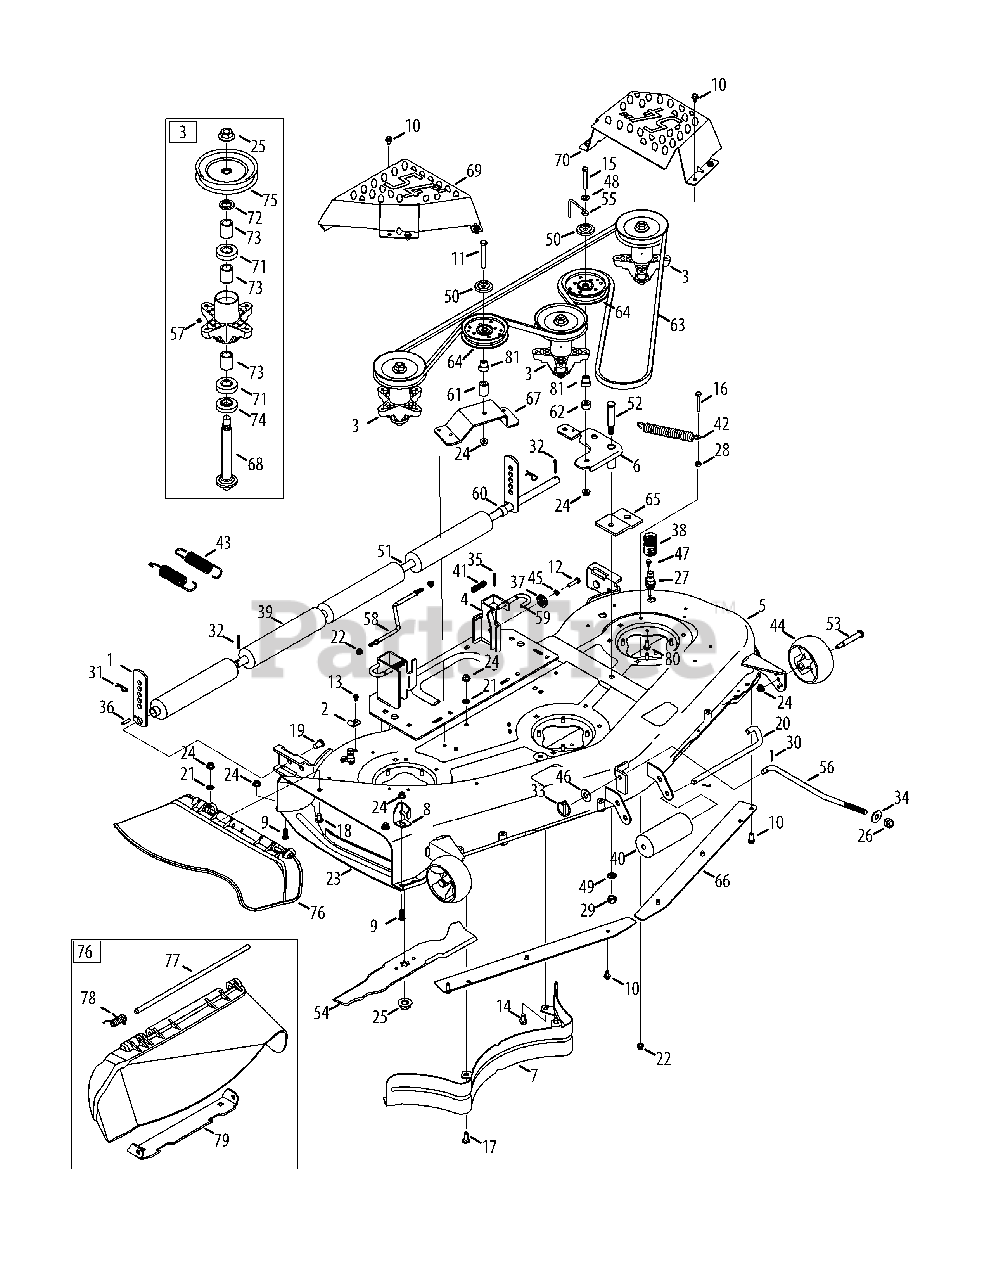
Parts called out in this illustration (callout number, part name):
1	Height Adjust Bracket
2	Retainer Hook Bracket
3	Spindle Assembly
4	Deck Hanger Bracket Assembly
5	Deck Shell
6	Idler Assembly
9	Hex Screw, 3/8-16 x 1.00
10	Taptite Screw, 5/16-18 x .750
11	Hex Screw, 3/8-16 x 3.00
12	Hex Screw, 5/16-18 x 1.25
13	Hex Screw, 1/4-20 x .500
14	Taptite Screw, 3/8-16 x 0.750
15	Hex Screw, 3/8-16 x 2.50
16	Hex Screw, 5/16-18 x 2.00
17	Carriage Bolt, 3/8-16 x 1.00
18	Carriage Bolt, 3/8-16 x 0.75
19	Clevis Pin, .50 DIA x .78 LG
20	Roller Pin, 1/2 DIA x 7.31 LG
21	Push Nut, 3/8
22	Flangelock Nut, 5/16-18
24	Flangelock Nut, 3/8-16
25	Flange Nut, 5/8-18
26	Flexlock Nut, 1/2-13
27	Deck Wash Nozzle
28	Hex Nut, 5/16-18
29	Hexlock Nut, Counterlock, 1/2-13
30	Cotter Pin, 3/32 x 1.0
31	Click Pin, .092 x 1.64 LG
32	Cotter Pin, 5/32 x 1.25
33	Lynch Pin, .1875
34	Washer, .630 x 1.25 x .180
35	Cotter Pin, 1/8 x 1.25
36	Spring Pin, 1/4 DIA x 1.00 LG
38	Water Nozzle Adaptor
39	Deck Roller
40	Front Roller
41	Compression Spring, .535 OD x 1.751 LG
42	Extension Spring, .85 OD x 5.915 LG
43	Extension Spring, 1.15 OD x 5.99 LG
44	Deck Wheel
45	Lock Washer, 5/16
46	Flat Washer, .531 x 1.25 x .100
47	Shoulder Screw, 1/4-20 x 0.50
48	Flat Washer, .406 x .875 x .059
49	Lock Washer, 1/2
50	Pulley Cap
51	Shaft, .750 x .47.12
52	Shield Screw, .625 x 2.50 x 1/2-13
53	Shoulder Bolt, .496 x 2.50 x 3/8-16
55	Belt Keeper Rod
56	Deck Lift Rod
57	Lube Fitting
58	Deck Sway Rod
59	Deck Release Handle Rod
60	Spacer, .82 ID x 1.00 OD x .53
61	Spacer, .380 x .900 x 1.313
62	Spacer, .385 ID x .88 x .64
64	Pulley, Idler, 4.25"Dia
65	Pulley Stabilizer Bracket
68	Spindle Shaft, 6.95 LG
69	RH Spindle Cover
70	LH Spindle Cover
71	Ball Bearing, .787 ID x 1.85 OD x .551
72	Spacer, .790 ID x 1.25 OD x .175
73	Spacer, .80 x 1.10 x 1.322 LG
74	Spacer, .79 x 1.82 x .55 LG
75	Deck Pulley
76	Chute Assembly
78	Torsion Spring, .44 ID x 2.0
79	Chute Bracket
80	Self Tapping Screw, 5/16-18 x .75
81	Shoulder Spacer
